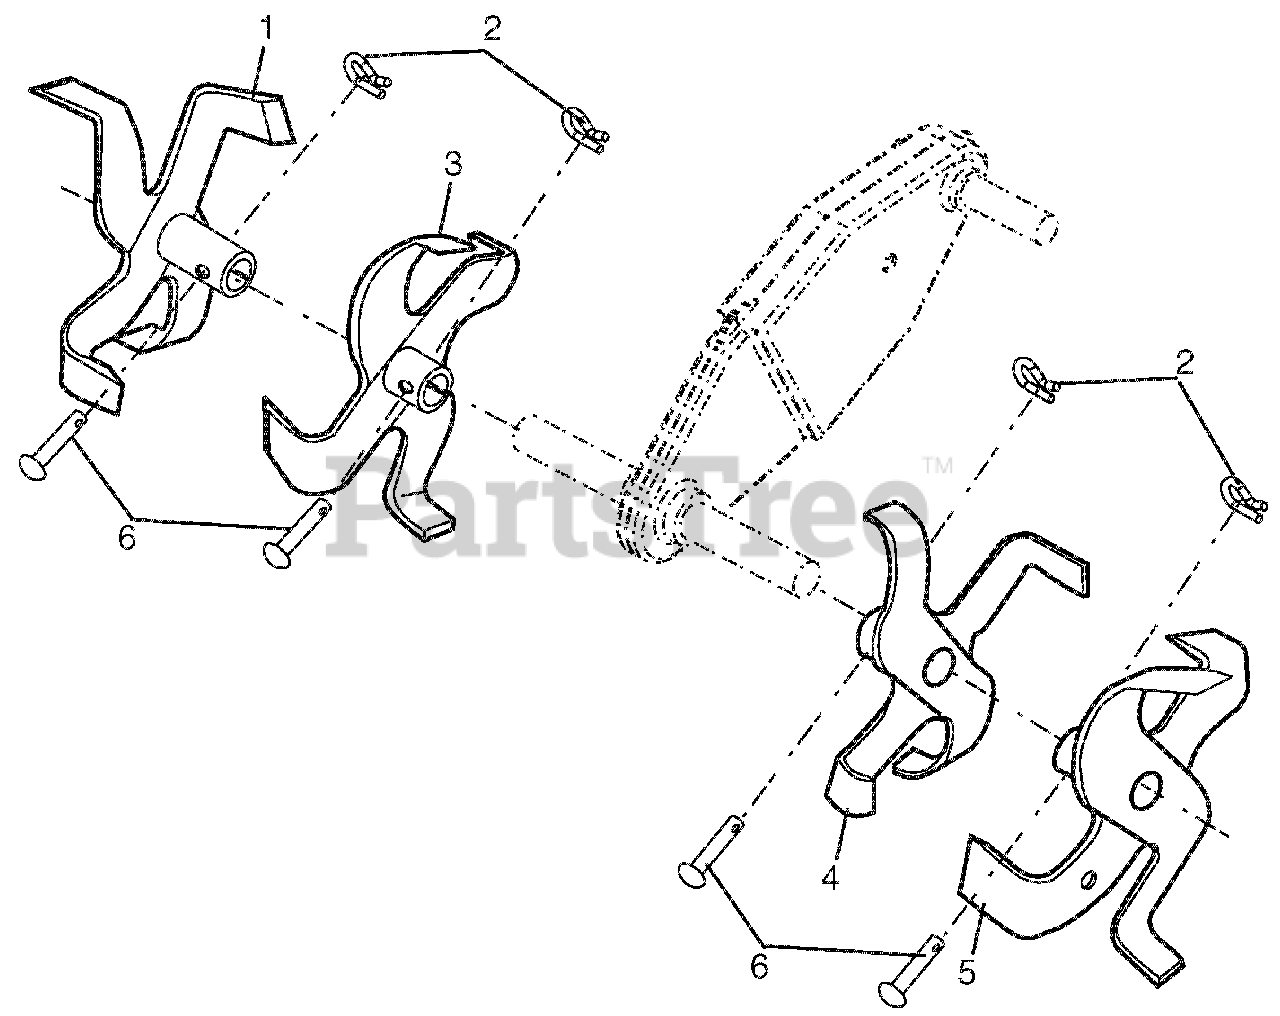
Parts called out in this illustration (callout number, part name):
1	TINE, OUTER, RH
2	Retainer, Spring
3	TINE, INNER, RH
4	TINE, INNER, LH
5	TINE, OUTER, LH
6	Pin, Clevis
